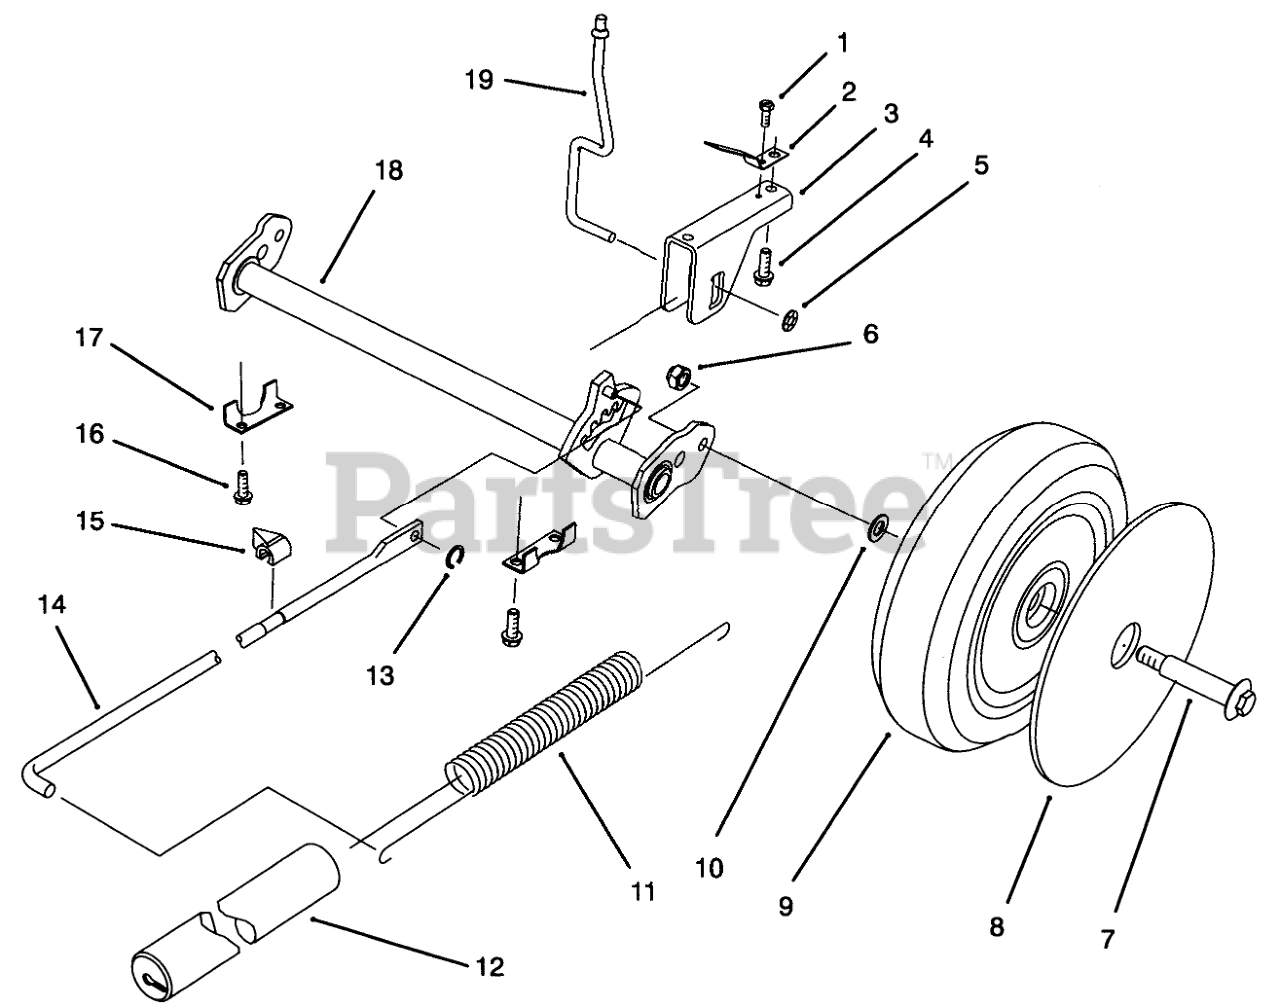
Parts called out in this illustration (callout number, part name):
1	SCREW 8 - 32 X 250
2	SPRING - TRIGGER RET
3	SADDLE - HOC
4	SCREW
5	PUSHNUT
6	NUT-HEX
7	BOLT-WHEEL
8	COVER-WHEEL
9	Wheel-ASM
10	WASHER
11	SPRING-COUNTERBALANCE
12	COVER-SPRING
13	GRIP RING
14	LINK ROD
15	INDICATOR-HEIGHT OF CUT
16	SCREW-HWH
17	REAR SECURING PLATE
18	PIVOT ARM REAR WA
19	TRIGGER ROD
